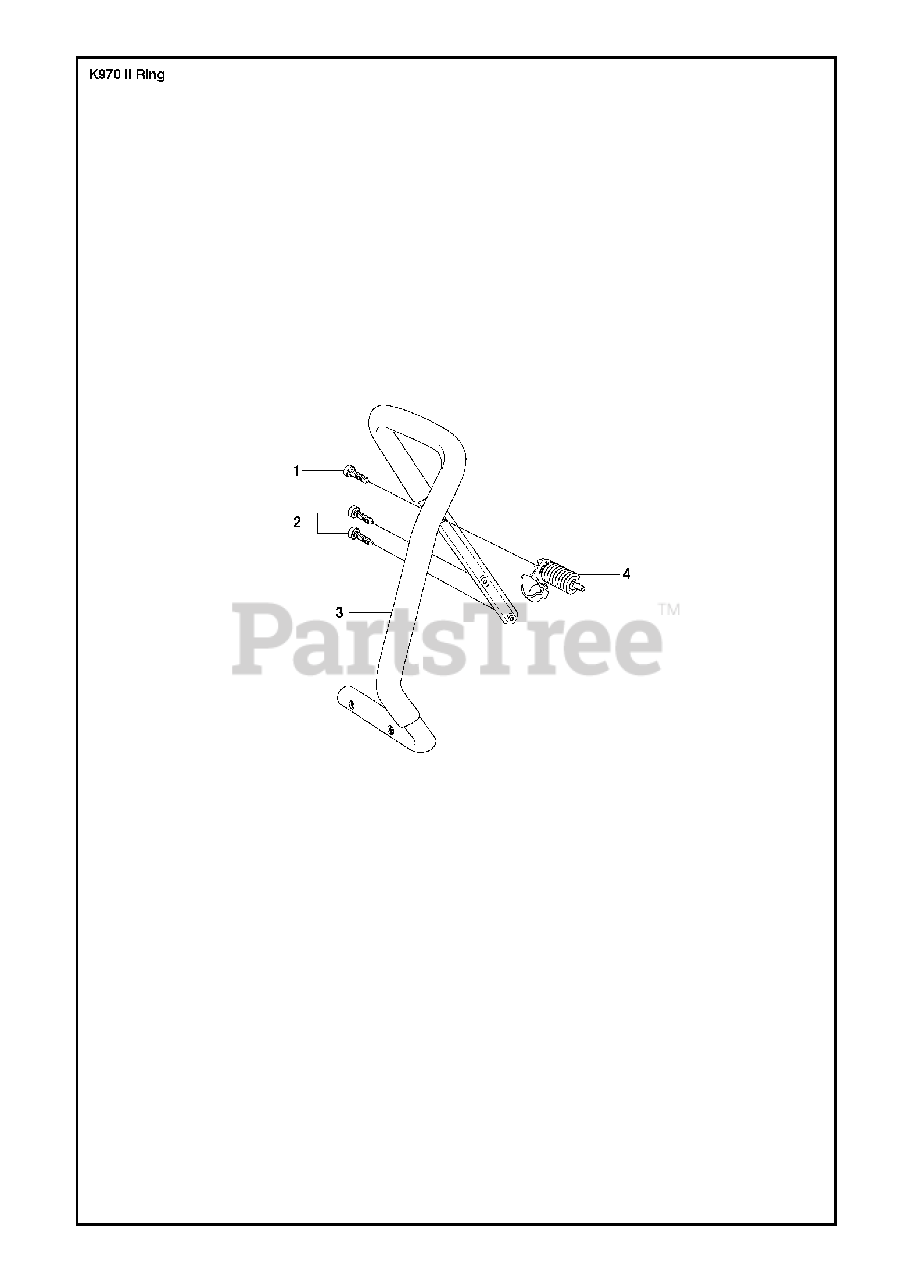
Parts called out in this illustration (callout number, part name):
1	SCREW ITXSCM
2	SCREW ITXSCT
4	ANTIVIBRATION ELEMENT
